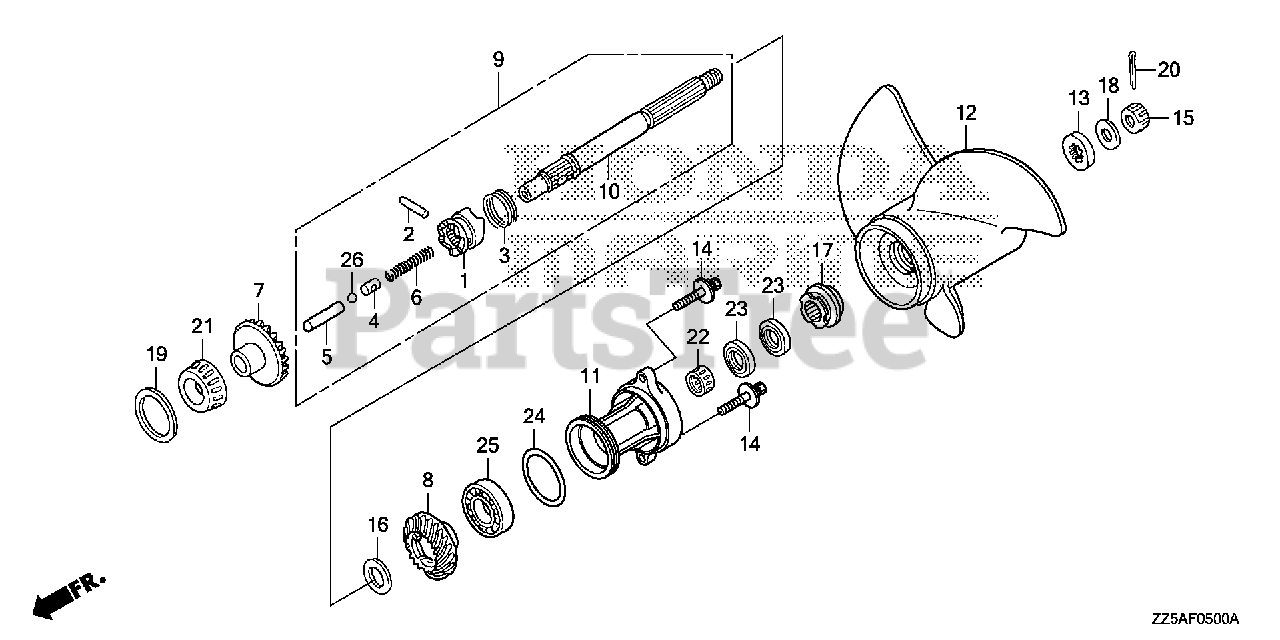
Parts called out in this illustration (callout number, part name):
1	SHIFTER, CLUTCH
2	PIN, SHIFTER (6.3X33)
3	RING, CROSS PIN
4	HOLDER, SHIFTER PIN
5	SLIDER, SHIFT
6	SPRING, SHIFT
7	GEAR, FR. BEVEL
8	GEAR, RR. BEVEL
9	SHAFT ASSY., PROPELLER
10	SHAFT, PROPELLER
11	HOLDER, PROPELLER SHAFT *NHB14M* (AQUA MARINE SILVER METALLIC)
13	SPACER (10MM)
14	BOLT-WASHER (8X30)
15	NUT, CASTLE (16MM)
16	WASHER (22MM)
17	WASHER, PROPELLER THRUST
18	WASHER (17MM)
19	SHIM, FR. BEVEL (51X57X0.10) (A)
19	SHIM, FR. BEVEL (51X57X0.15) (B)
19	SHIM, FR. BEVEL (51X57X0.30) (C)
19	SHIM, FR. BEVEL (51X57X0.50) (D)
20	PIN, SPLIT (4.0)
21	BEARING (32X58X17)
22	BEARING, NEEDLE (22X28X20)
23	SEAL, WATER (22X35X7)
24	O-RING (69X3.1)
25	BEARING, RADIAL BALL (6007)
26	BALL, STEEL (#11) (11/32)
